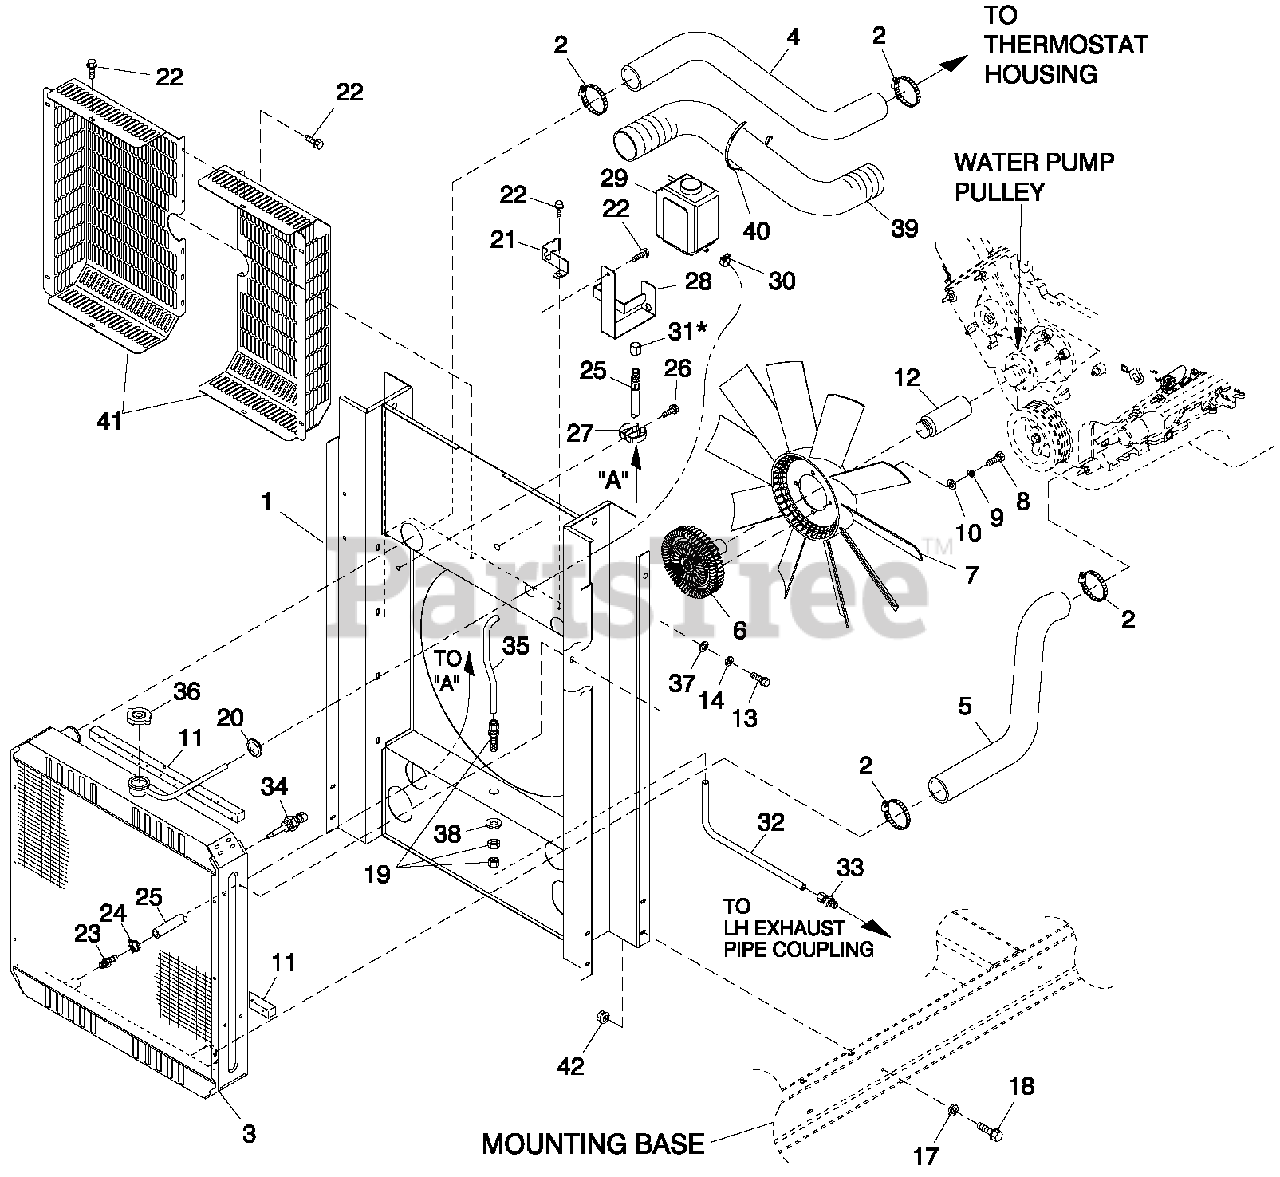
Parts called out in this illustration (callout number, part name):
1	WELDMENT RAD SUPPORT C3 (22")
2	CLAMP HOSE #281.32-2.25
3	RADIATOR 581 X 585 X 70 CPL LH
4	HOSE UPPER RADIATOR C3
5	HOSE LOWER RADIATOR C3
6	CLUTCH COOLING FAN
7	FAN 22" DIA10 BLADE
8	SCREW HHC M10-1.5X 20 G8.8
9	WASHER LOCK M10
10	WASHER FLAT 3/8-M10 ZINC
11	TAPE FOAM 1 X 1 (23" LG)
12	SPACER FAN 6.8L
13	SCREW HHC M8-1.25X 20 G8.8
14	WASHER LOCK M8-5/16
17	WASHER LOCK M6-1/4
18	SCREW HHFC M6-1.0X20 G8.8
19	FTG CMPN BLKHD 3/8" OD TUBE BRS
20	GROMMET.75X.12X.50
21	BRACKET SIGNAL CONDITIONER
22	SCREW THF M6-1 X 16 N WA Z/JS
23	BARBED STR 3/8 NPT X 3/8
24	CLAMP HOSE .38-.87
25	HOSE DRAIN ASSY 28"
26	SCREW HHTT M4-0.7X8BP
27	SPRING CLIP HOLDER .37-.62
28	BRKT COOLANT RECOVERY TANK
29	TANK COOLANT RECOVERY
30	CLAMP HOSE BAND 1/4
31	CAP HEX 1/4 NPT BRASS
32	TUBE FAN CLUTCH PREHTR LOWR C3
33	FTG CMPR 3/8TUBE X 3/8 NPT W/FERL
34	PROBE COOLANT LEVEL 3/8 NPTF (USE WITH HARN P/N 0F5990 & 0F5991)
35	TUBE FAN CLUTCH PREHTR UPPR C2
36	CAP RADIATOR 13 PSI
37	WASHER FLAT 5/16-M8 ZINC
38	WASHER FLAT 9/16 ZINC
39	CONDUIT FLEX 2.0"ID
40	TIE WRAP UL 14.6 X.14 BLK
41	GUARD FAN C3 CPL
42	NUT FLANGE M6-1.0NYLOK
